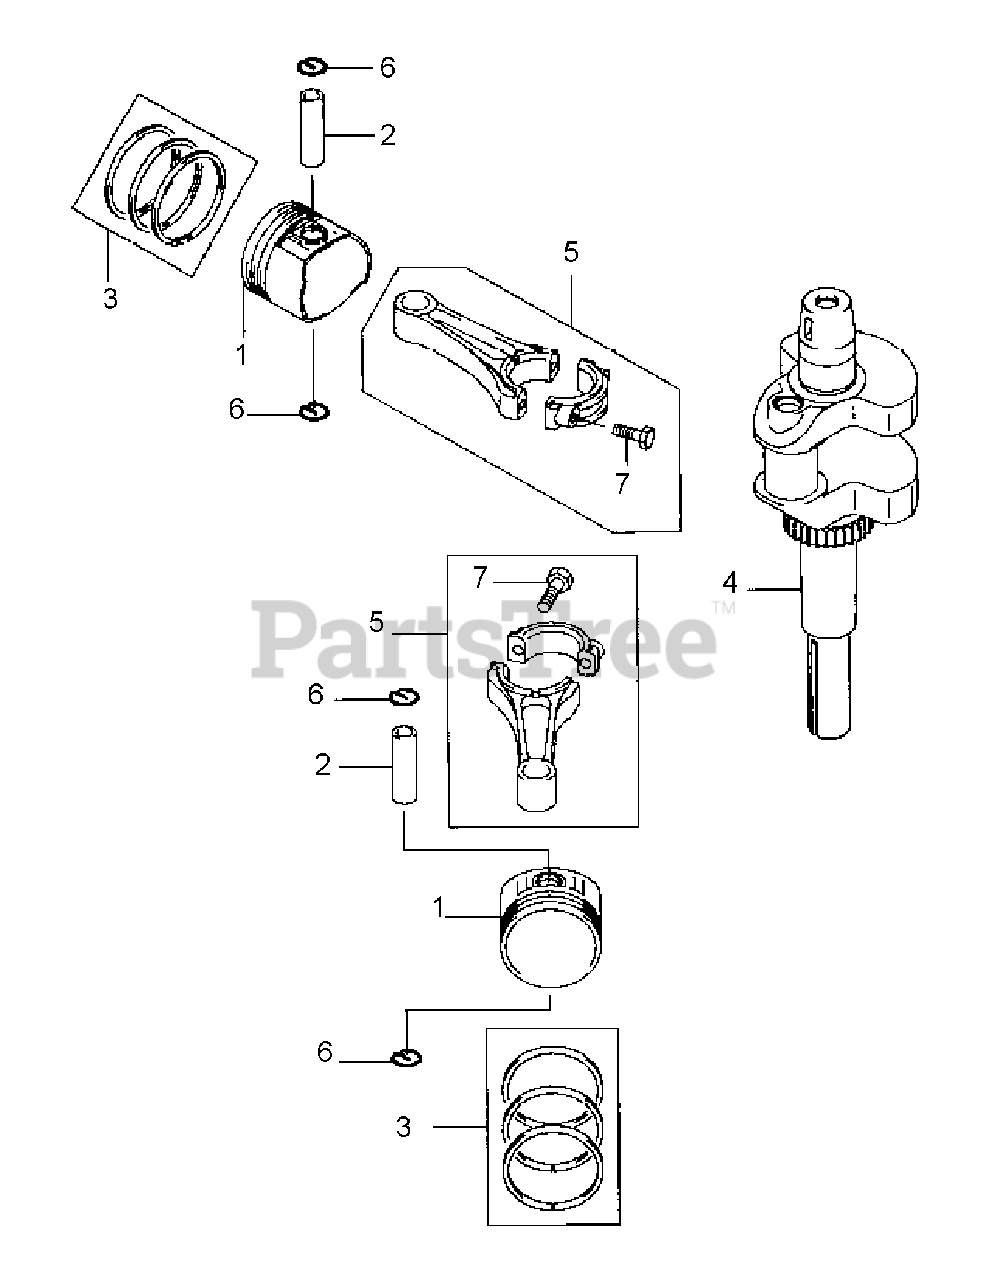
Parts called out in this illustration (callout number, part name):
1	PISTON-ENGINE
1	PISTON-ENGINE L, 0.50
3	RING-SET-PISTON
3	RING-SET-PISTON L, 0.50
4	CRANKSHAFT-COMP
5	ROD-ASSY-CONNECTING
5	ROD-ASSY-CONNECTING, U/S=.50
7	BOLT-FLANGED
